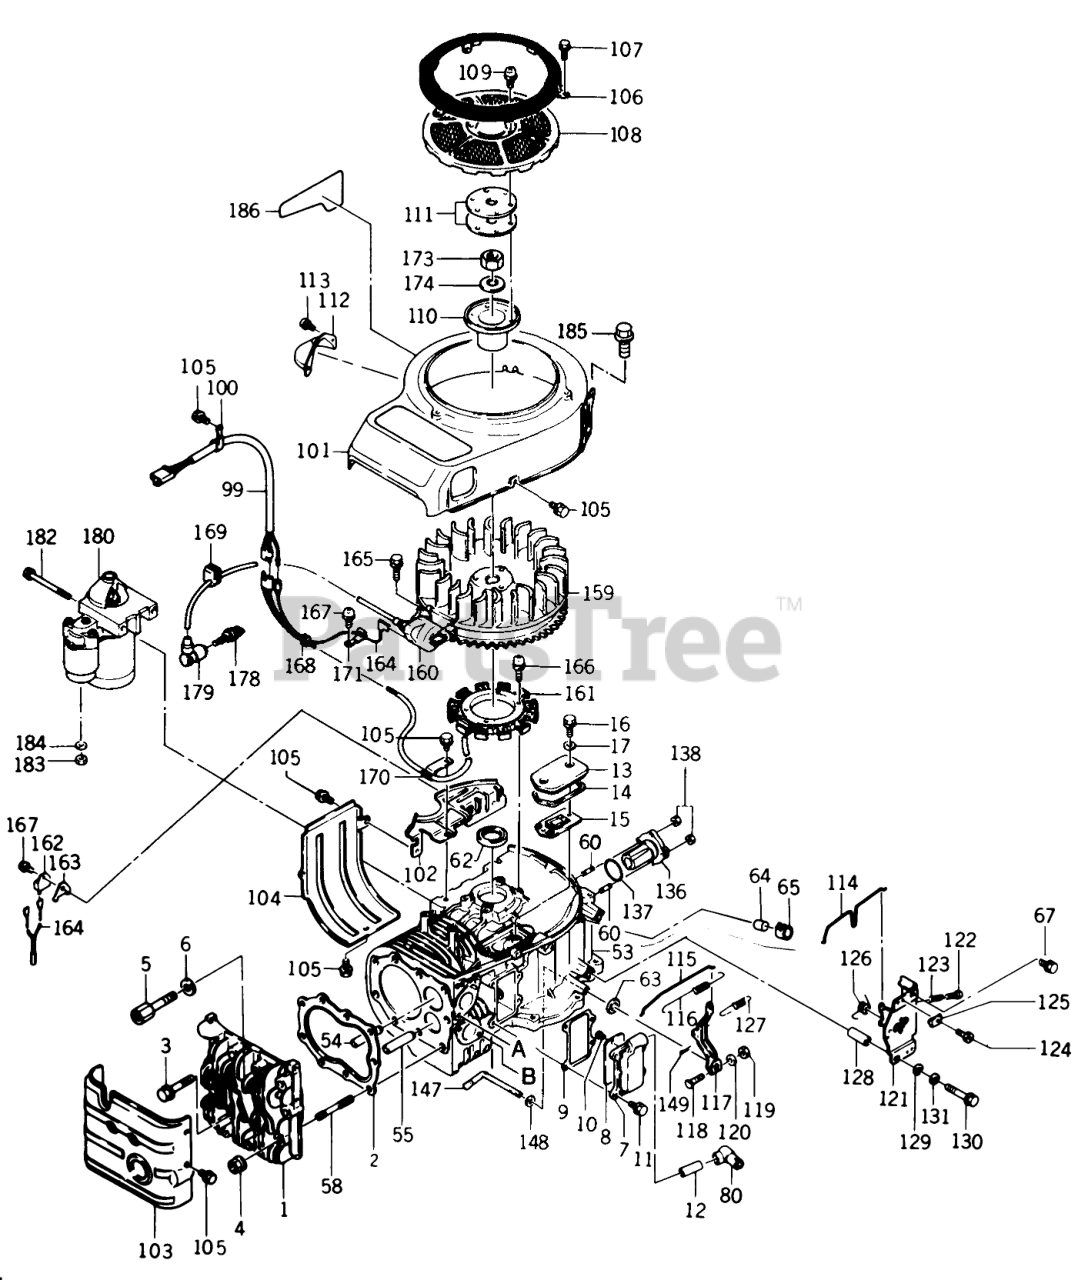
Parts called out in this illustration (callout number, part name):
1	Cylinder Head
2	Head Gasket
3	BOLT 10X55
6	Washer
7	COVER
8	COVER
9	GASKET
10	SCREW
11	Bolt
13	COVER
14	GASKET
15	BREATHER
17	GASKET-OIL GAUGE
53	Crankcase Complete (includes items 54 & 55)
54	GUIDE-VALVE
55	VALVE-GUIDE
62	SEAL OIL
63	SEAL-OIL, VC (6X10X2.5)
64	SEAL-OIL, VC (6X10X2.5)
65	SEAL-OIL, VC (6X10X2.5)
67	BOLT-FLANGED
80	JOINT
100	CLAMP
101	Fan Housing
102	HOUSING-FAN
103	SHROUD
104	Shroud
105	BOLT-FLANGED
106	PROTECTOR
107	Bolt
108	SCREEN
109	SCREW-PAN-WP-CROS
110	BRACKET
112	COVER
113	SCREW 4X8
116	SPRING
117	GOVERNOR ARM COMP
118	Bolt
119	NUT 6MM
120	Washer
121	Control Panel Assy (includes items 122, 123, 124, 125 & 126)
122	SCREW PAN HEAD 4X25
123	SPRING
125	CLAMP
126	SPRING
127	Spring
128	COLLAR
129	WASHER, CLUTCH
130	BOLT 6X50
131	WASHER-SPRING 6MM
136	SHAFT
137	O-RING
138	Nut
147	ARM-GOVERNOR
148	WASHER-PLAIN 6MM
149	Pin
159	FLYWHEEL ASSY
160	IGNITION COIL
161	COIL-CHARGING
162	IGNITER
163	BRACKET
164	WIRE-LEAD
166	SCREW-PAN-WP-CROS
167	SCREW 4X8
168	GROMMET
169	GROMMET
170	CLAMP
171	CLAMP
173	NUT 18MM
174	WASHER
178	Plug-Spark
179	CAP-SPARKPLUG
180	STARTER ASSY ELECTRI
183	NUT-8M/M
184	WASHER 5/16 SAE
185	Bolt
